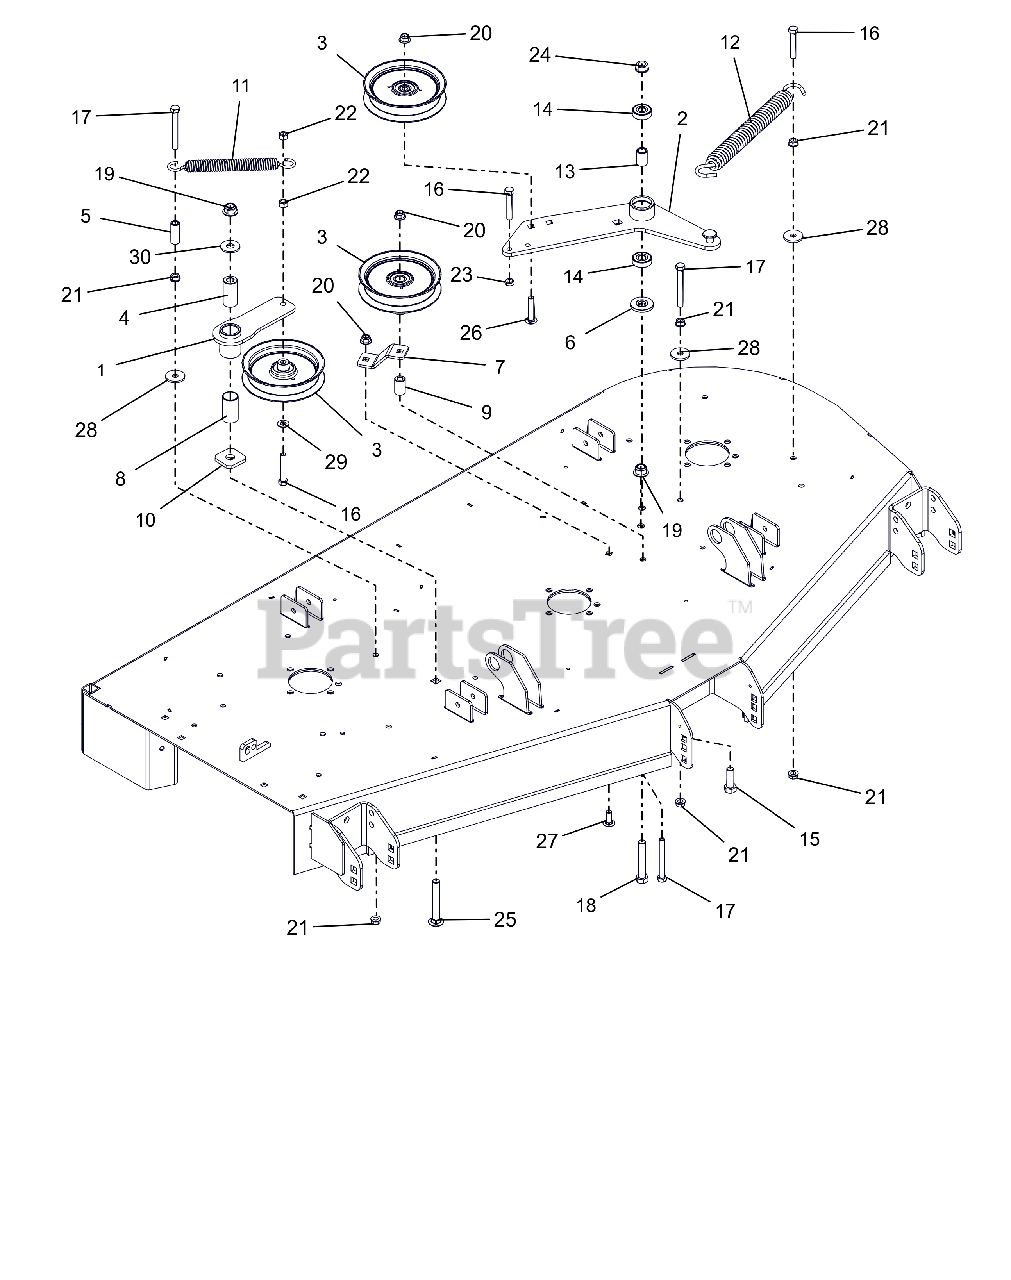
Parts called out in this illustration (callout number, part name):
1	WMT, IDLER ARM - BLACK
2	DECK PTO IDLER ARM WLDMT - BLK
3	IDLER, FLAT 5.00"
4	BSHG, SPCR .502X.997X2.03 PM
5	SPACER, .375IDX.625ODX1.66 PM
6	SPACER, IDLER ARM
7	PTO FIXED IDLER MTG BRKT-ORG
8	BSHG, 1.00X1.125X1.937
9	BUSHING, SLV .380X.750X1.190
10	WSHR-FLT .640X1.75X.250
11	SPRING, EXTENSION
12	SPRING, EXTENSION
13	SPACER .510 X .75 X 1.1485
14	BRG-BALL .500X1.38X.437
15	BLT,HEX .50-13X1.50 G5 ZCC
16	BLT,HEX .38-16X2.25 G5 ZCC
17	BLT, HEX .38-16X3.25 G5 ZCC
18	BLT, HEX .50-13X3.00 G5 ZCC
19	NUT,NYL-FLG .50-13 GF ZCC
20	NUT,NYL-FLG .38-16 GF ZCC
21	NUT, SPNLK-FLG .38-16 G5 ZCC
22	NUT-LK-CTR .38-16 ZC120
23	NUT-JAM .375-16 G2 ZCC
24	NUT-LK-CTR-FLG .500-13 GG ZCC
25	BLT, RHSN .50-13X3.50 G5 ZCC
26	BLT,RHSSN.375-16X2.00 G5 ZCC
27	BLT,RHSSN .38-16X1.00 G5 ZCC
28	WSHR,FLT .406X1.375X.135 ZCC
29	WSHR,FLT .406X.812X.065 ZCC
30	WSHR,FLT .563X1.375X.109 ZCC
